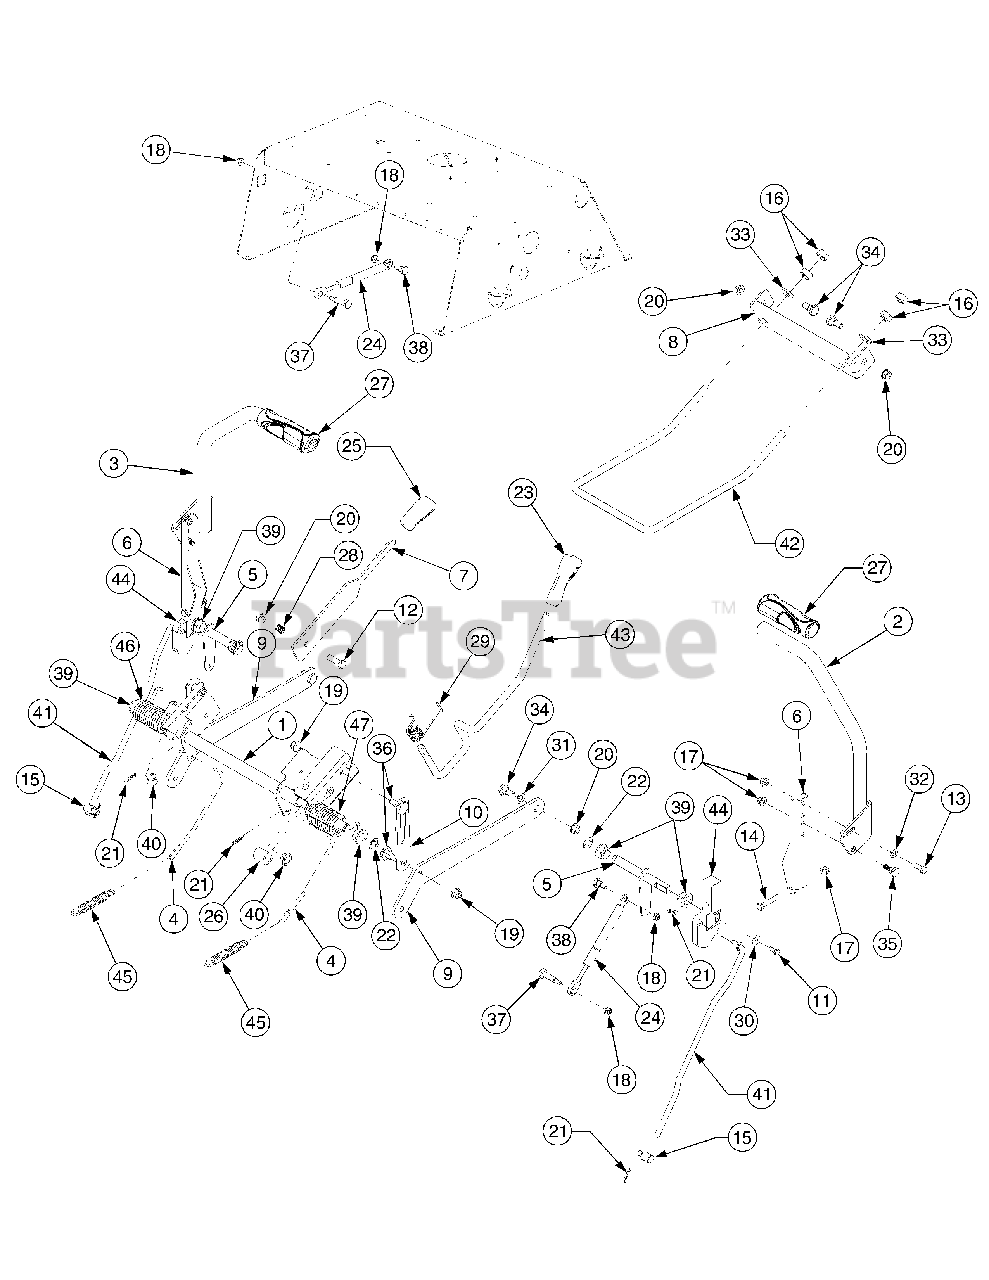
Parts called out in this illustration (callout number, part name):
4	Rod, Brake
5	Shaft, Control
6	Bracket, Lapbar Pivot
11	Screw, Hex Lock, 1/4-20 x .62 GR5
12	Screw, Hex Cap, 3/8-16 x 1.25 GR5
13	Screw, Hex Cap, 5/16-18 x .75 GR5
14	Screw, Hex Cap, 5/16-18 x 1.75 GR5
15	Ferrule, 3/8-24 x .375
16	Nut, Hex, 1/2-13 GR5
17	Nut, Hx Flange Insert Lck, 5/16-18 GrF
18	Nut, Hx Flange Insert Lck, 1/4-20 GrF
19	Nut, Hx Flange Insert Lck, 3/8-16GrF
20	Nut, Hex Flange Lock, 3/8-16 GRF
21	Pin, Internal Cotter
22	E-Ring , .625 Dia. Shaft
23	Grip, Handle
24	Cylinder, Damper
25	Grip, Handle
26	Spacer, .62 x 1.0
27	Grip, Hand
28	Spring, Compression
29	Spring, Torsion RZT
30	Washer, Bell, .265 x .75 x .062
31	Washer, Flat, .51 x 1.0 x .06
32	Washer, Flat, .344 x .688 x .065
33	Washer, Flat, .531 x 1.062 x .134 HT
34	Screw, Shoulder, .498 x .340:3/8-16
35	Screw, Shoulder, .437 x .268:5/16-18
36	Screw, Shoulder, .5 x .434:3/8-16
37	Screw, Shoulder, .374 x 1.16:1/4-20
38	Screw, Shoulder, .375 x .38:1/4-20
39	Bearing, Hex Flange
40	Bearing, Flange, .626 x .938 x .344
41	Rod, Lapbar Control
42	Rod, Deck Front Hanger
43	Rod, Deck Lift Handle
44	Hub, Control
45	Spring, Extension, .59 x 4.0
46	Spring, Torsion LH
47	Spring, Torsion RH
